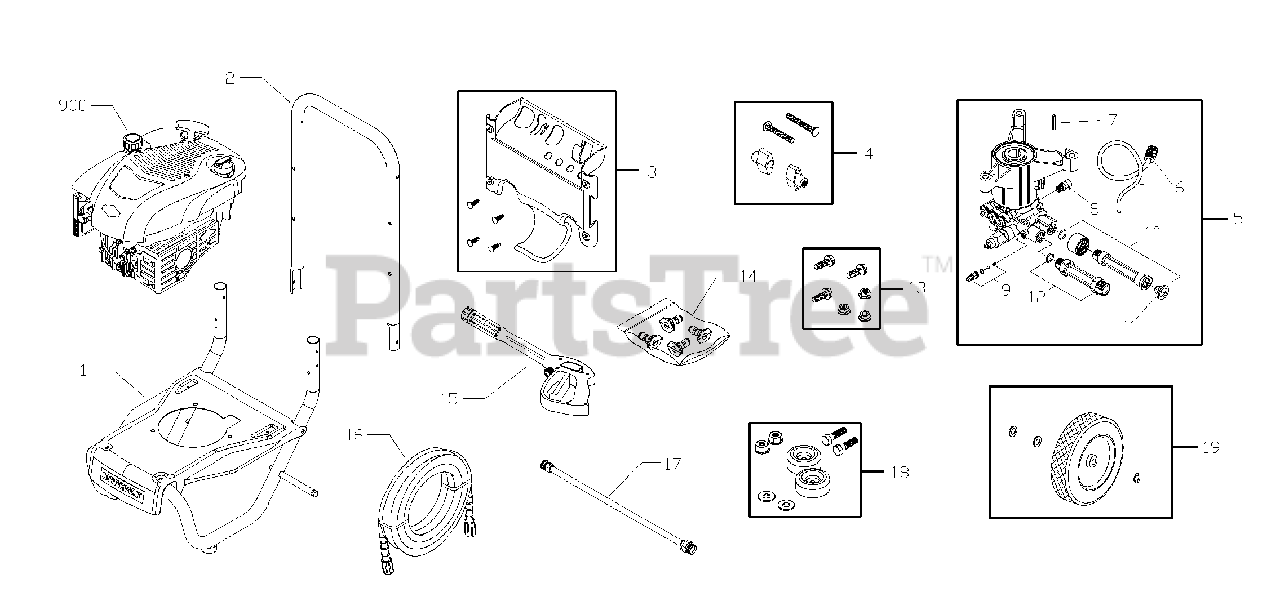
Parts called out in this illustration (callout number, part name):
2	HANDLE
4	KIT, Hardware Handle
5	PUMP
6	KIT, Chemical Hose
8	VALVE, Thermal Relief
9	KIT, Chemical Injection
10	KIT, Water Inlet
11	FILTER, Garden Hose
13	KIT, Hardware Pump Mounting
14	KIT, QC Nozzles
15	GUN
16	HOSE
17	EXTENSION, QC
18	KIT, Vibration Mount
900	*ENGINE
